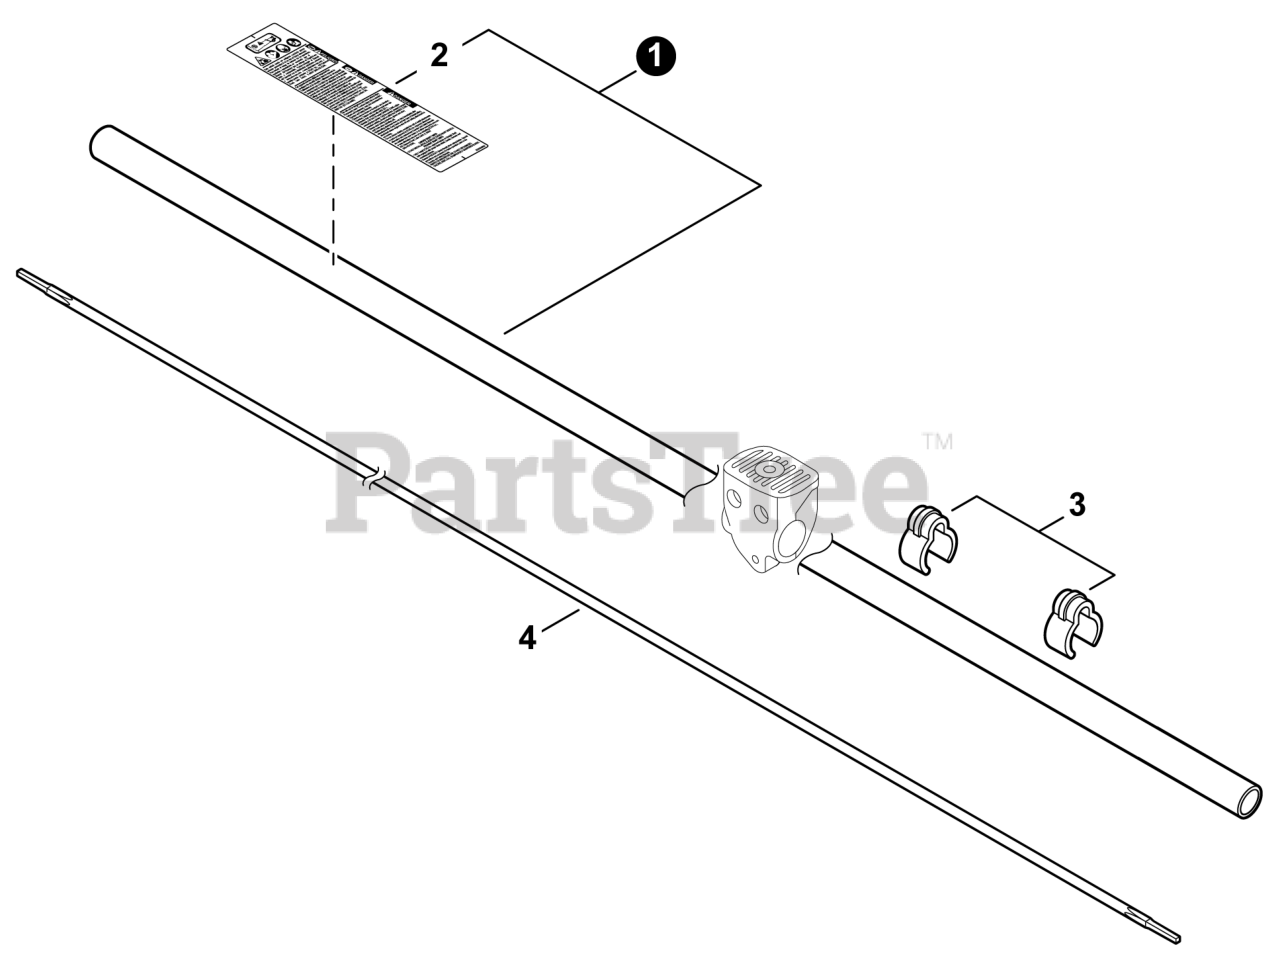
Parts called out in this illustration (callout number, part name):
1	MAIN PIPE ASSY
2	LABEL - CAUTION
3	CLIP, CABLE 25 MM
4	DRIVESHAFT - FLEXIBLE
